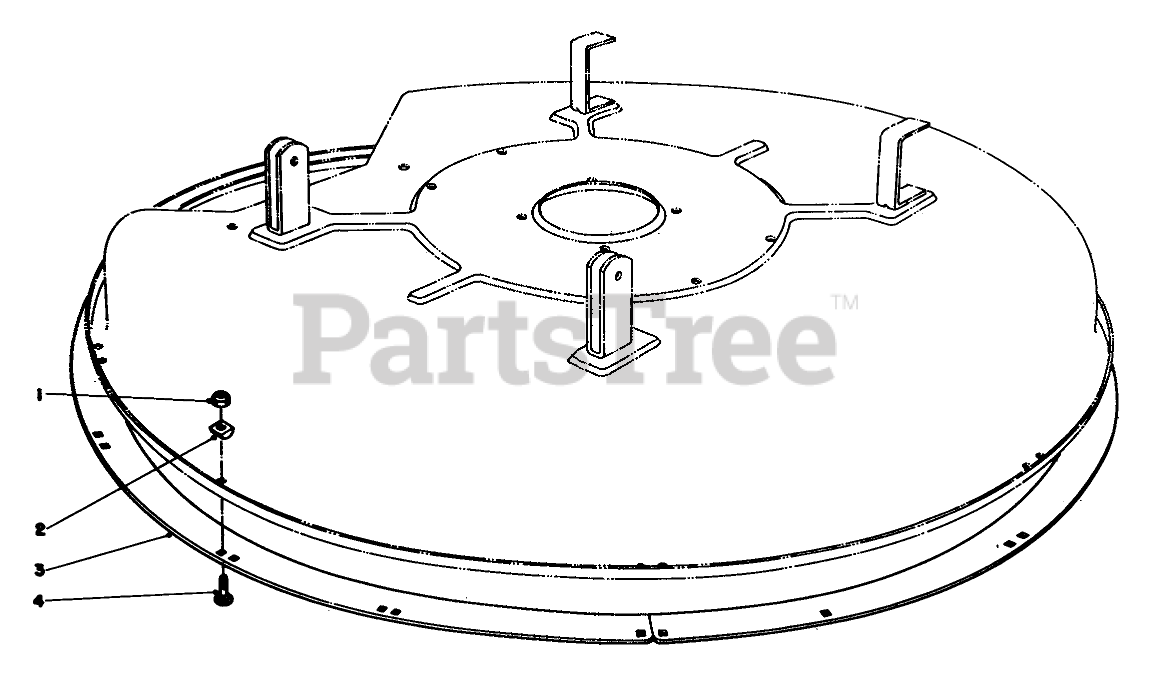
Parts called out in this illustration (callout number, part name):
1	NUT-LOCK, NI
2	Spacer-Deck Ring
3	DECK RING B
4	BOLT-CARR
